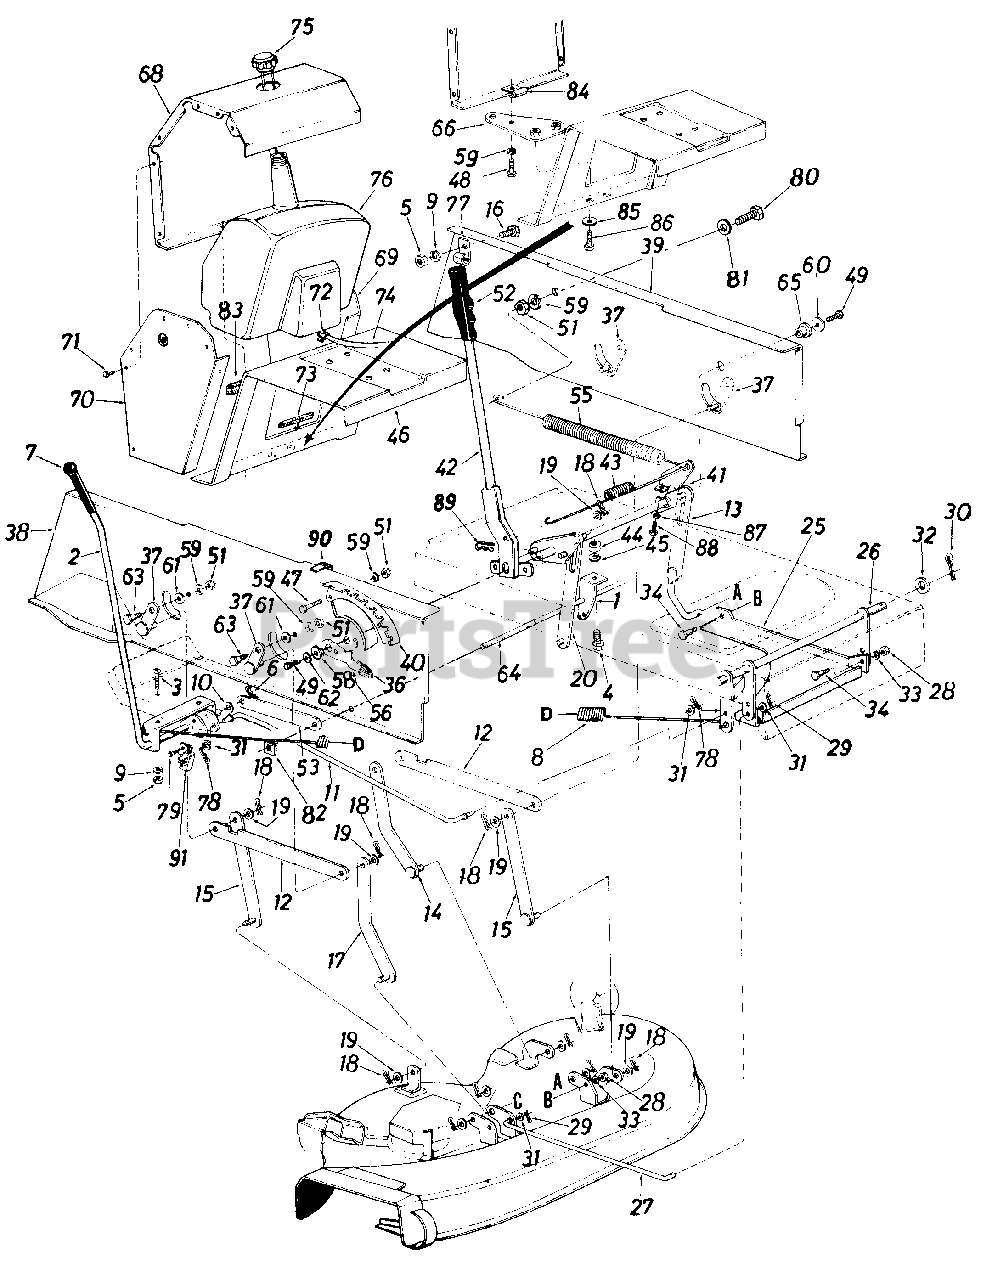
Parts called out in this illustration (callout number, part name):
1	Spring Hanger Bracket
2	Deck Engagement LeverAss'y.
3	Truss Mach. Scr. 5/16-18 x.75 " Lg .
4	Hex Bolt 1/4-20 x .62" Lg.
5	Hex Nut 5/16-18 Thd.
6	Cotter Pin 3/32" Dia. x 1.00" Lg.
8	Ext Spring .99" O.D. x 22" Lg.
9	L-Wash. 5/16" I.D.
10	Fl-Wash. .510" I.D. x 1.0" O.D.
11	Drive Deck Control Rod
12	Connecting Rod 3/16 x 1 x 12.5
13	Deck Lift Link Ass'y.
14	Deck Hanger Link Ass'y.-Rear L.H.
15	Deck Hanger Link Ass'y.
16	Hex Bolt 5/16-18 x .75" Lg.
17	Deck Hanger Link Ass'y.-Front R.H.
18	Inter. Cotter Pin 1/2" Dia.
19	Fl-Wash. .531 I.D. x .93" O.D.
20	Link Deck Lifting Ass'y.
25	Diagonal Brace
26	Stabilizer Shaft Ass'y.
27	Stabilizer Rod
28	Hex Nut 3/8-16 Thd.
29	Cotter Pin 3/32" Dia. x 1.0" Lg.
30	Cotter Pin 1/8" Dia. x 1.25 Lg.
31	Fl-Wash. .385" I.D. x .620" O.D.
32	Fl-Wash. .635" I.D. x 1.12" O.D.
33	L-Wash. 3/8" I.D.
34	Shoulder Bolt 3/8-16
36	Knob-Height Adj.
37	Pivot Link Ass'y.
38	Side Panel Upper Frame-R.H.
39	Side Panel Upper Frame-L.H.
40	Index Brkt.
41	Lift Shaft Ass'y.
42	Lift Handle Brkt. Ass'y.
44	Hex Nut 1/4-20 Thd.
45	L-Wash. 1/4" I.D.
46	Hitch Plate
47	Hex Bolt 5/16-18 x .75" Lg.'
48	Hex Bolt 5/16-18 x 1.00" Lg. (Grade 5)
49	Hex Wash. TT-Tap Scr. 5/16-18 x .62" Lg.
51	Hex Nut 5/16-18 Thd.
52	Grip
53	Link 1.0" x 7.5" x .19
55	Ext. Spring .99" Dia. x 11.00" Lg.
56	Deck Lift-Down Stop
58	Flange Brg. .630" I.D.
59	L-Wash. 5/16" I.D.'
60	Fl-Wash. .344" I.D. x 1.125" O.D. x .125
61	Fl-Wash. .344" I.D. x .62" O.D. x .063
62	Fl-Wash. .344" I.D. x 1.125 O.D.
63	Shld. Bolt .437" Dia. x .180
64	Running Board Rod
65	Flange Brg. .632" I.D.
66	Hitch Bar Ass'y.
68	Gas Tank Housing-Main Panel
69	Side Panel-L.H.-Gas Tank
70	Side Panel-R.H.-Gas Tank
71	Truss Mach. B-Tapp Scr. #10 x .50" Lg.
72	Hose Clamp-.406" Dia.
73	Trim Strip-5" Lg.
74	Gas Line-44" Lg.
75	Gas Tank Cap
78	Cotter Pin 3/32" Dia. x .75 Lg.
79	Hex Wash. Hd. Tap Scr. 1/4 x.50" Lg.
80	Hex Bolt 5/16-18 x 1.50" Lg.
81	Fl-Wash. .344" I.D. x .875" O.D.
82	Speed Nut for .500" Dia. Stud
83	Foam Strip 3/8" x 1-1/8" x 11/2" Lg.
84	U-Nut 5/16-18 Thd.
85	Bell-Wash. .385" I.D. x .88"
86	Hex Wash. Tap-Scr. 3/8-16 x .75" Lg.
87	Hex Jam Nut 5/16-18 Thd. (Grade 5)
88	Hex Wash. Hd. Tap Scr. 5/16-18 x 1" Lg.
89	Internal Cotter Pin 3/8" Dia.
91	Safety Switch
